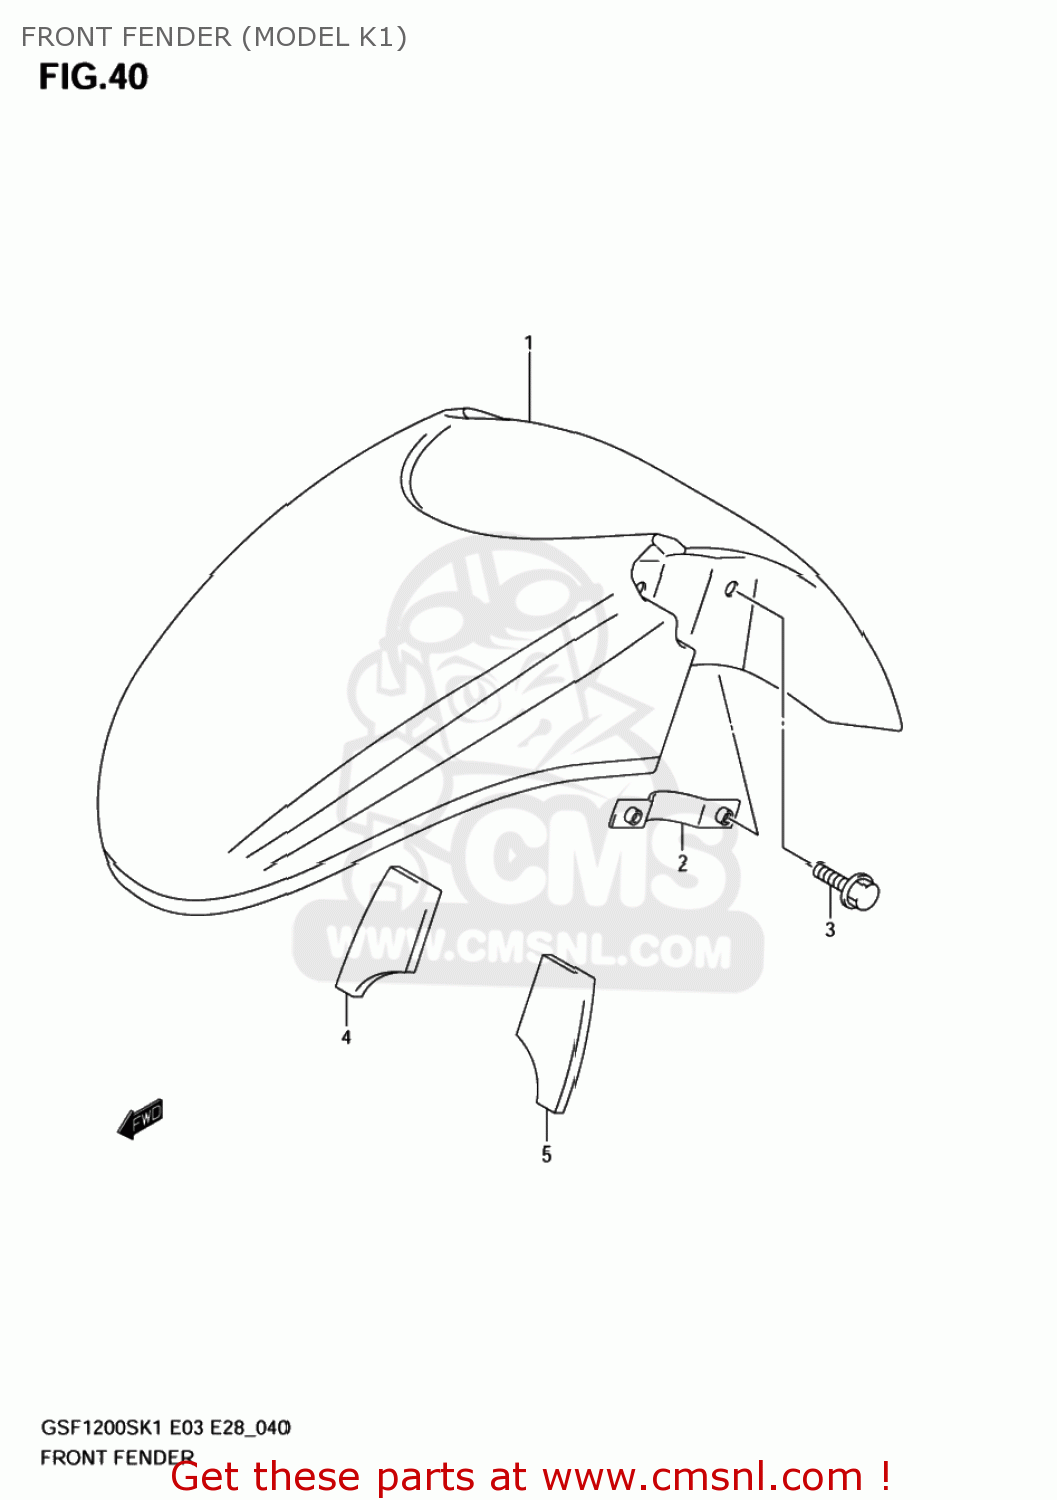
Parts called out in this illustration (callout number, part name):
1	FENDER,FR
2	PLATE,FR FENDER
3	BOLT
4	CUSHION,FR FENDER,R
5	CUSHION,FR FENDER,L
